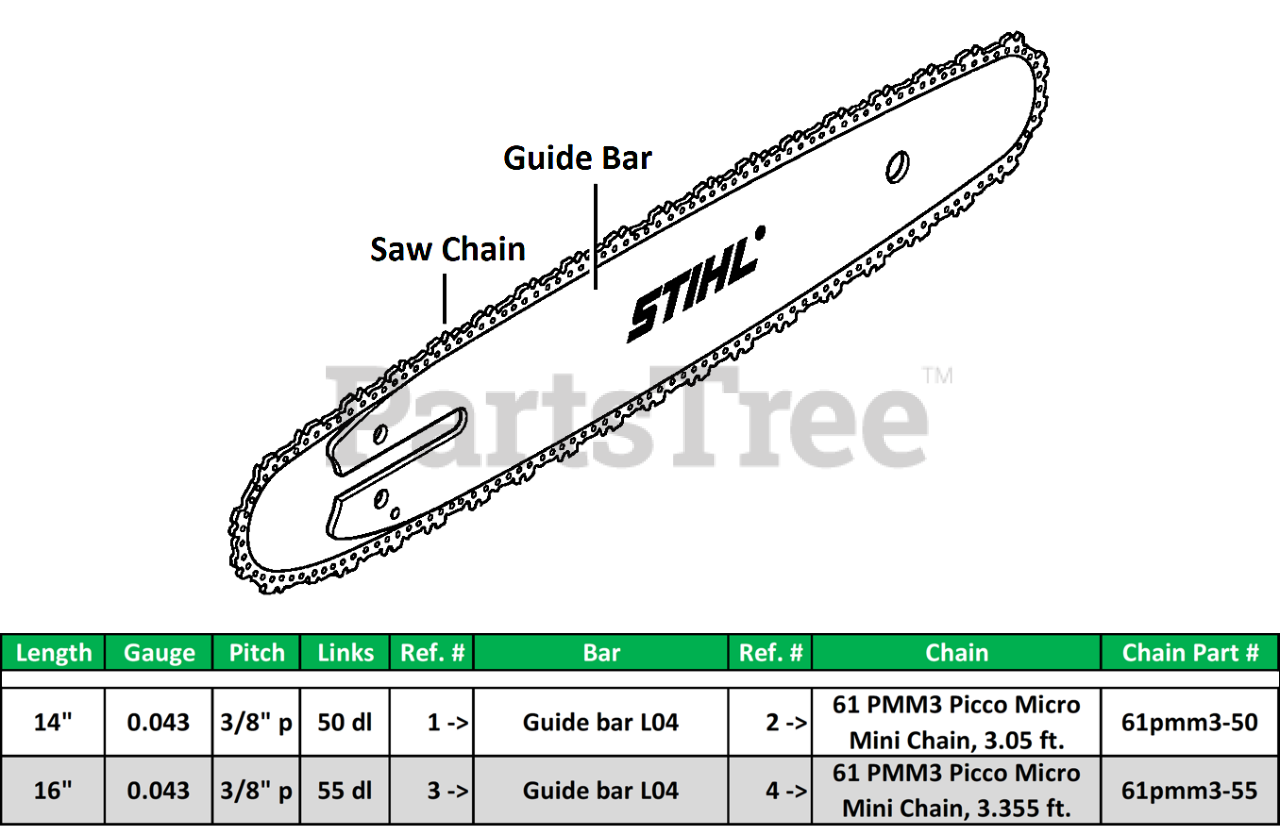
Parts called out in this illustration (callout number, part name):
1	Guide Bar L04 35cm/14" 1,1mm/0.043" 3/8" P
2	61 PMM3 Picco Micro Mini Chain, 3.05 ft.
3	Guide Bar L04 40cm/16" 1,1mm/0.043" 3/8" P
4	61 PMM3 Picco Micro Mini Chain, 3.355 ft.
